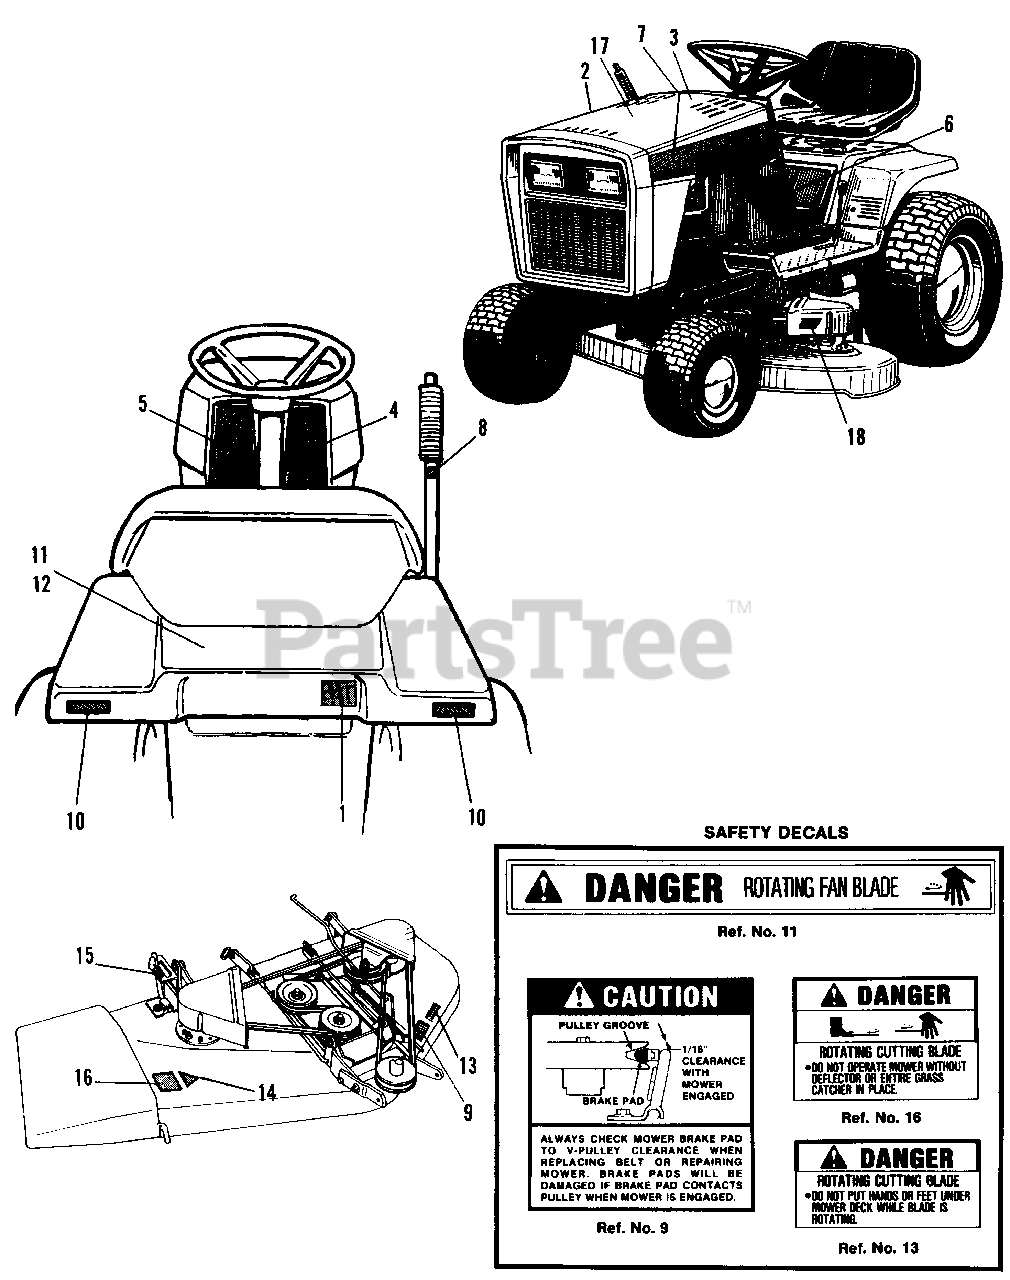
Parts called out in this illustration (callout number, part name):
1	DECAL, Model 16GTH
1	DECAL, Model 17GTH
2	DECAL, Hood Stripe, R.H.
3	DECAL, Drive Belts (1691736)
4	DECAL, Dash, R.H.
5	DECAL, Dash, L.H.
6	DECAL, Shift Pattern
7	DECAL, Hood Stripe, L.H.
8	DECAL, Lift Lever
9	DECAL, Danger
10	REFLECTOR, Rear
11	DECAL, Warning, Fan (Under Seat Deck)
12	DECAL, Release Valve (Under Seat Deck)
13	DECAL, Danger
14	DECAL, OPEI
15	DECAL, Mower Height
16	DECAL, Danger
17	DECAL, Touch-Up Paint
18	DECAL. 42"
